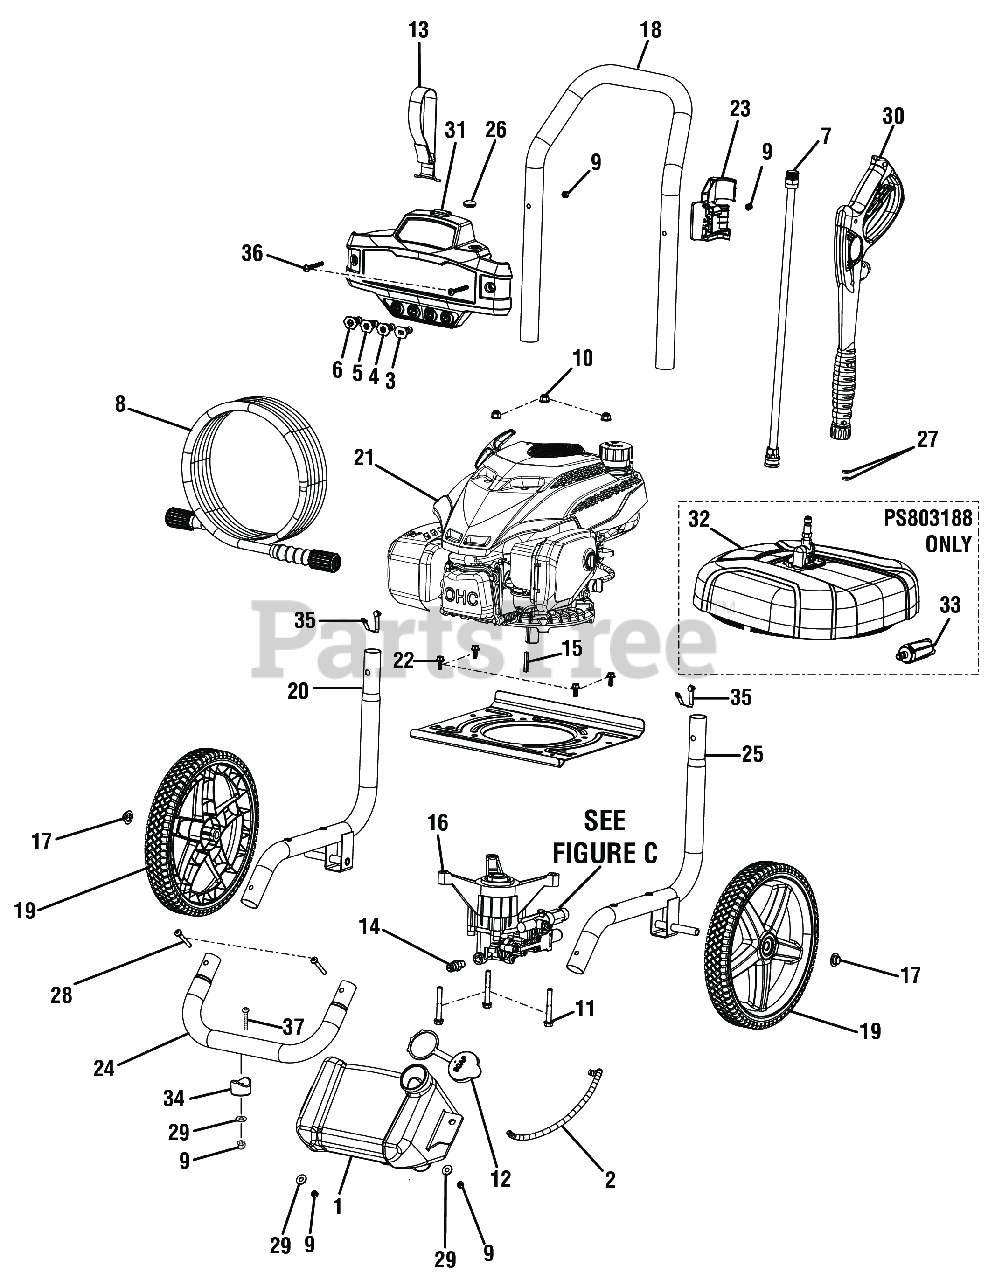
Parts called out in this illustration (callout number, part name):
1	Soap Tank
2	Detergent Injection Hose
3	Soap Nozzle (Blue)
4	40deg Deg Nozzle
5	25deg Deg Nozzle
6	15deg Deg Nozzle
7	Extension Wand
8	Hose (30 ft.)
9	Lock Nut (M6 x 1)
10	Lock Nut (M8 x 1.25 mm, Flange)
11	Flange Bolt (M8 x 1.25 x 60 mm, Hex Hd.)..
12	Detergent Tank Cap
13	Hose Holder Strap
14	Thermal Release Valve.
15	Output Shaft Key ( 35 mm)
16	Pump (See Figure B)
17	Push Cap Nut (1/2 in.)
18	Handle Assembly
20	Main Frame Assembly
21	Engine
22	Flange Bolt (M6 x 1 x 16 mm, Hex Hd.)
23	Wand Holder
24	Front Frame Assembly
25	Main Frame Assembly
26	Rubber Nozzle Grommet
27	O-Ring (9.5 x 2.65, NBR Shore A 90)
28	Screw (M6 x 1 x 48 mm, T30 Torx Pan Hd.)
29	Washer (1/4 in.)
30	Trigger Handle Assembly
31	Performance Panel
32	14 in. Surface Cleaner (PS803188)
33	Turbo Nozzle (PS803188)
34	Rubber Foot
35	Lock Button w/Spring Clip.
36	Bolt (M6 x 48 mm, Button Hd.)
